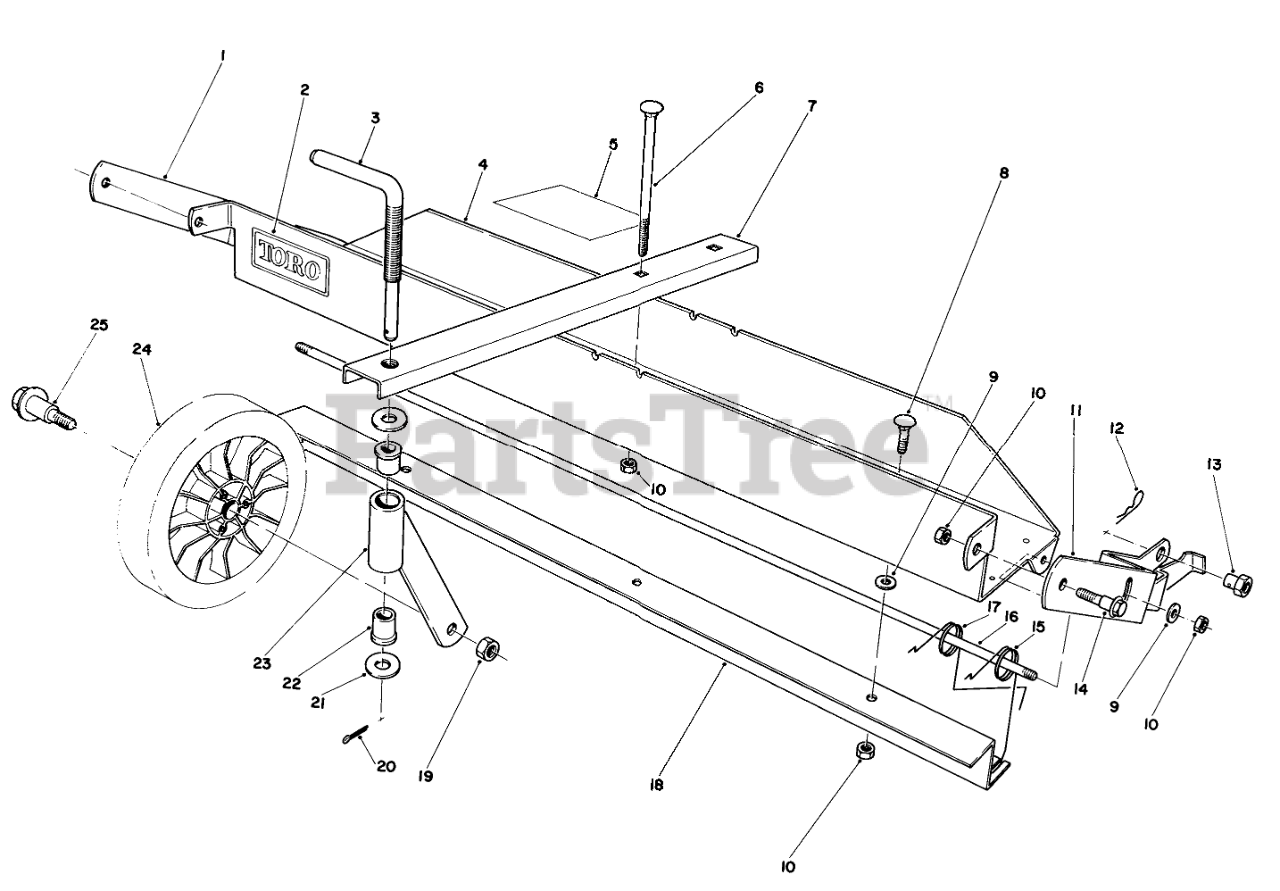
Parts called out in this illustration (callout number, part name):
1	Frame R.H.
2	Decal-Toro
3	CASTOR ADJ ROD
4	Frame-Main (Incl. Ref. #2)
5	Decal-Instruction
6	SCREW-CARR
7	Castor Frame
8	BOLT-CARR
9	WASHER-FLAT
10	NUT-HEX, SIDE DEFORM
11	LH MTG FRAME
12	PIN-COTTER, HAIR
13	PIVOT NUT
14	SCREW-SHOULDER
15	DETHATCHER SPRING
16	SPRING SUPPORT ROD
17	DETHATCHER SPRING
18	SPRING GUIDE STRAP
19	Nut
20	PIN-COTTER
21	WASHER-FLAT
22	FLANGE BUSHING
23	Castor Tube & Support
24	Wheel Assembly
25	BOLT-WHEEL
